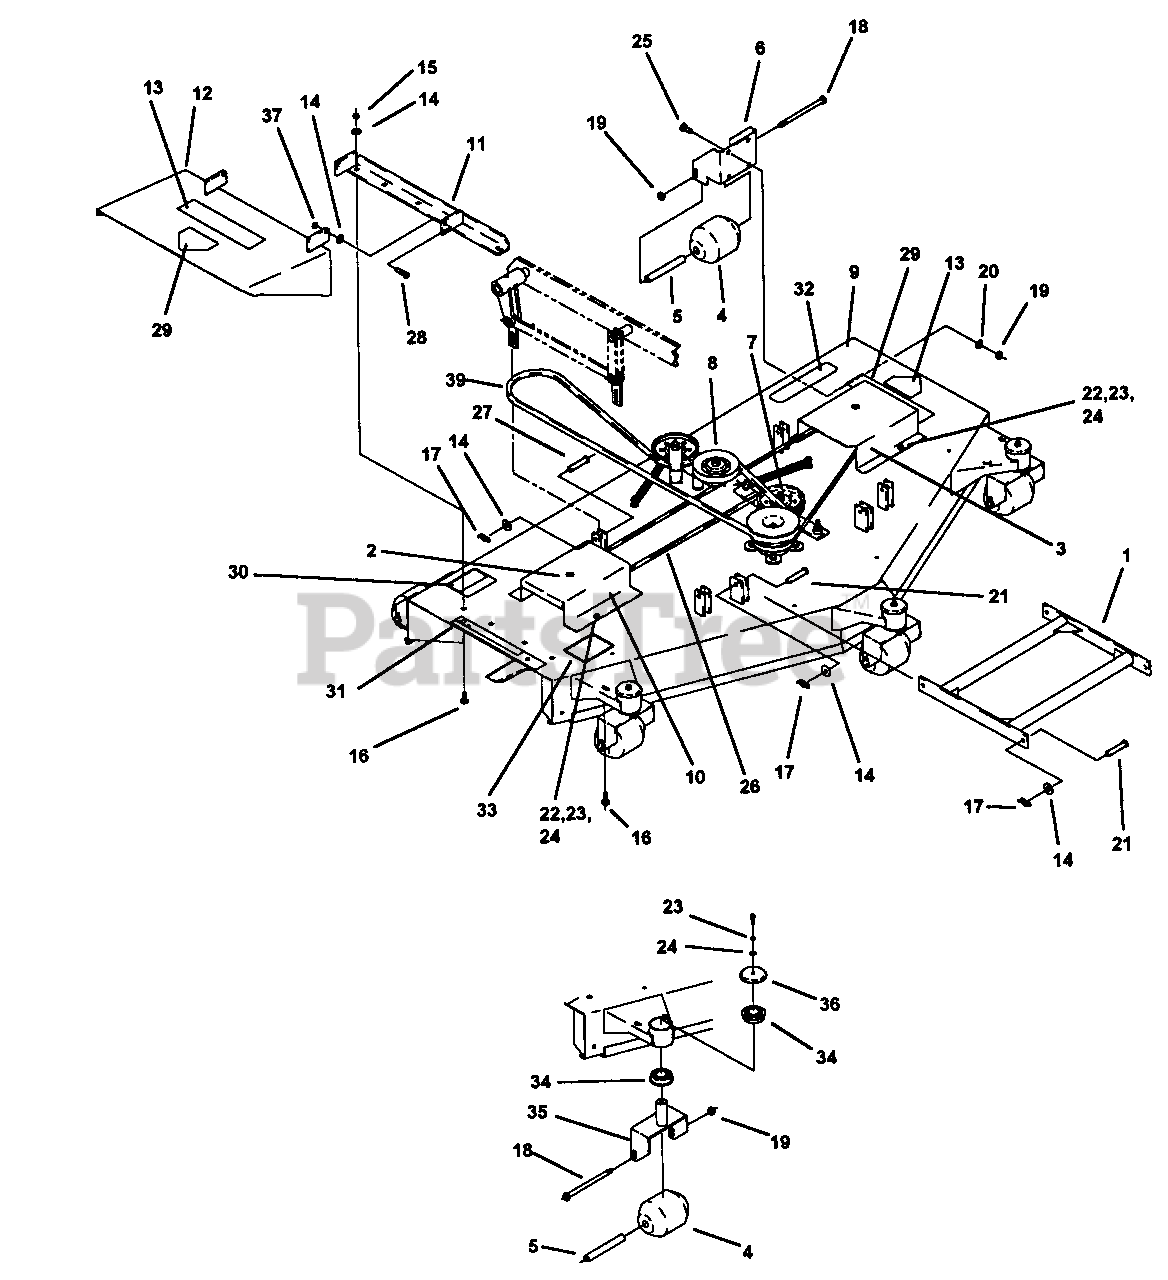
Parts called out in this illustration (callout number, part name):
1	DRAG BAR WELDMENT
2	SPINDLE ASSEMBLY
3	PULLEY COVER, L.H. 6O" DECK
4	ROLLER, 3-3/4 X 4-13/16" LONG (B)
5	BUSHING (B)
6	BRACKET, REAR CENTER
7	SINGLE IDLER PARTS
8	DOUBLE IDLER ASSEMBLY
10	PULLEY COVER, R.H. BO" DECK
11	OUTLET STIFFENER WELDMENT, BO" DECK
12	CHUTE WELDMENT (w/decal)
14	WASHER, FLAT STD. 5/16"
15	NUT, 5/16-18 NYLOC p)
16	BOLT, 5/16-18 X 3/4" CARRIAGE
17	COTTER PIN, SELF LOCKING, 5/16 - 3/8
18	BOLT, 3/8-16 X 6" GR.5
19	NUT, 3/8-16 NYLOC
20	WASHER, FLAT STD. 3/8"
21	CLEVIS PIN, 5/16 X 1-1/4" LONG
22	BOLT, 1/4-20 X 3/4" GR.5
23	LOCKWASHER, 1/4" SPLIT SPRING
24	WASHER, FLAT STD. 1/4"
25	BOLT, 3/8-16 X 7/8" GR.5
26	DECK CROSS BELT, A-112
27	CLEVIS PIN, 5/16 X 1-1/2" LONG
28	BOLT, 5/16-18 X 1" GR.5.
29	DECAL, "MULTI-PERIL"
30	DECAL, "WARNING- ROTATING BLADES"
32	DECAL, "MODEL #Z6004M"
33	DECAL, "GREASE SPINDLES"
34	BEARING, SPD SF-16-32 NO/COLLAR
35	SWIVEL YOKE WELDMENT
36	CAP, BEARING
37	LOCKNUT, 5/16-18 STOVER
39	ENGINE TO DECK BELT, BP-81
